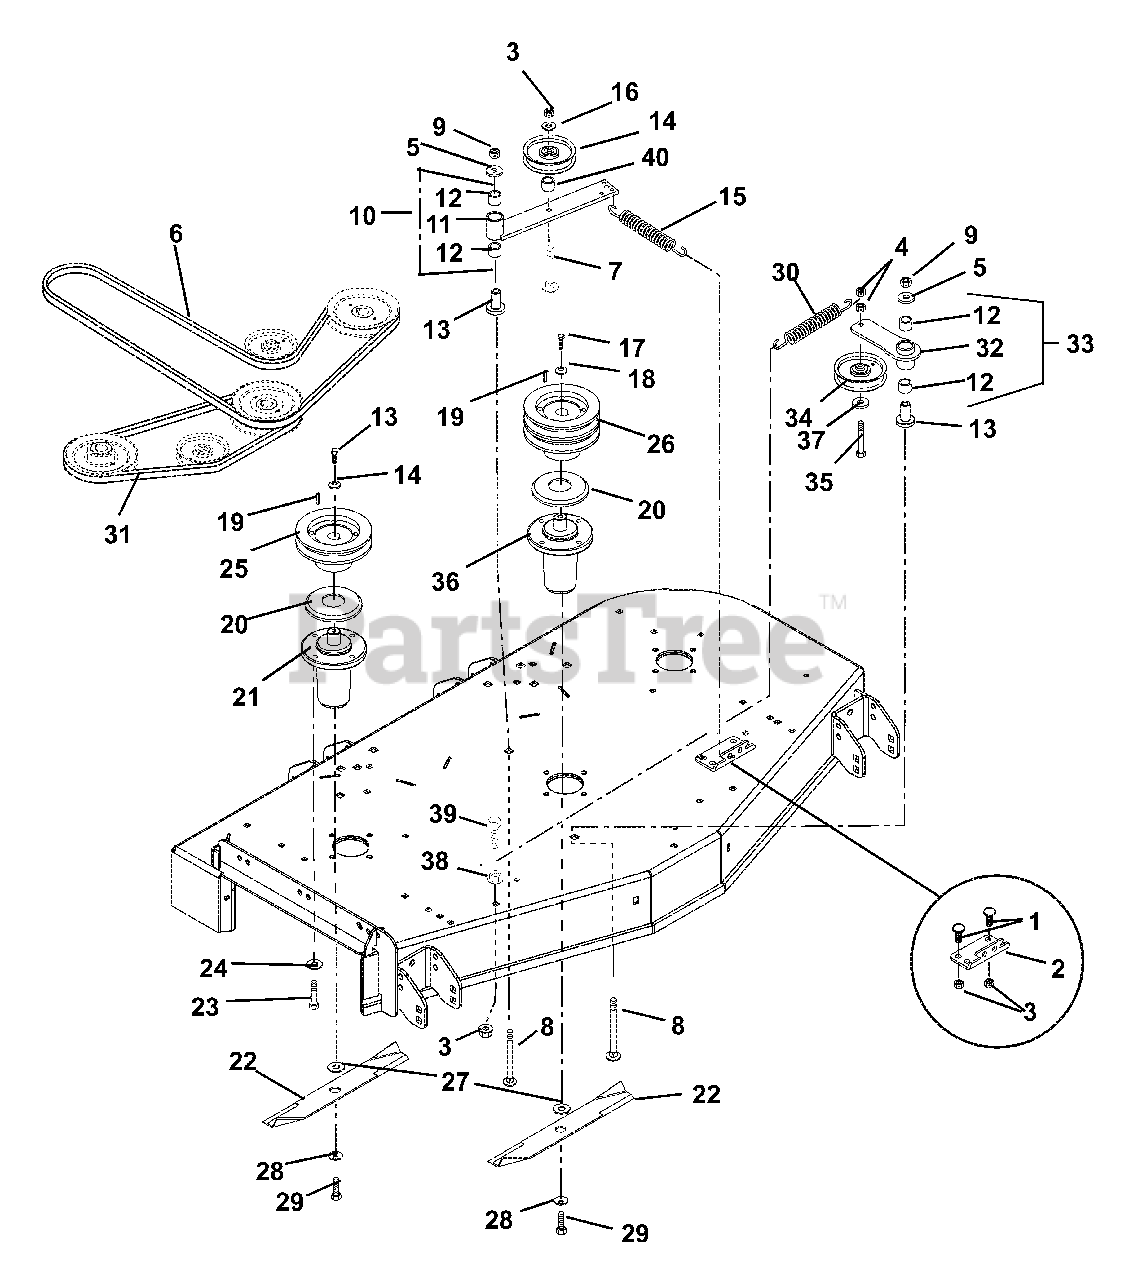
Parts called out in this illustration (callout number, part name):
1	Bolt, Round Head Square Neck .38-16 x .75 Grade 5
2	Bracket, Spring
3	Nut, Locking Top Flange .38-16
4	Nut, Locking Center .38-16
5	Washer, Flat Steel .531 x 1.25 x .10
6	V-Belt, B-Section 51.50 x .625
7	Bolt-Round Head Square Neck .38-16 x 2.25 Grade 5
8	Bolt, Round Head Square Neck .50-13 x 3.50 Grade 5
9	Nut, Locking Top Flange .50-13
10	Assembly, Idler Pivot Arm
11	Weldment, Idler Pivot Arm
12	Bearing, 1.00 x 1.12 x .75
13	Bearing, Pedestal Powdered Metal
14	Idler, Flat 4.00 x .38 (1.00 W)
15	Spring, Extension
16	Washer, Flat Steel .375 x 1.125 x .065
17	Bolt, Hex .38-16 x 1.00 Grade 8
18	Washer, Cupped Serrated .375
19	Key, Square .25 x .25 x 1.00 RC 40-50
20	Slinger, Dust
21	Assembly, Maintenance Free Spindle
22	Blade, Mower
22	Blade, Mulching
23	Bolt, Hex .38-16 x 1.00 Grade 5
24	Washer, Locking .38 x .094 Regular
25	Weldment, Spindle Sheave 5.00
26	Sheave, Double (5.25)
27	Washer, Flat .64 x 1.81 x .250
28	Washer, Bellville .63 x 1.625 x .14
29	Bolt, Hex .62-18 x 1.75 Grade 8
30	Spring, Extension
31	V-Belt, 5L-Section 49.97 x .672
32	Arm, Idler Pivot
33	Asm, Idler Pivot Arm
34	V-Idler, 4.00 x .38
35	Bolt, Hex .38-16 x 2.25 Grade 5
36	Spindle Assembly (Center)
37	Washer, Flat Steel .406 x .812 x .065
38	Nut-Flange .375-16
39	Bolt-Hex .38-16 x 3.50 Grade 5
40	Spacer .380 x .750 x .236
